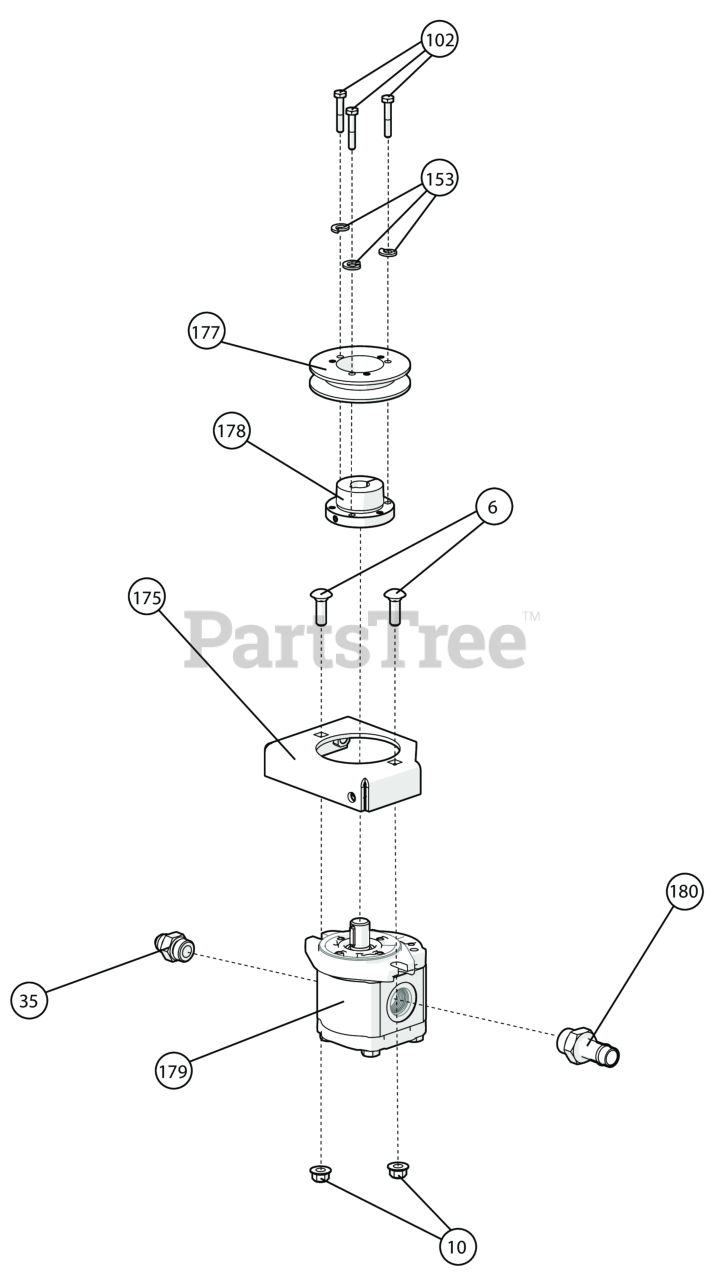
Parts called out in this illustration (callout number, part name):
6	BOLT CARRIAGE 3/8"-16 X 1 1/4" ZP
10	NUT-HEX-NYLK, FLG .375"-16 ZP
35	ADAPTER, HYDRAULIC, SAE-10 TO 1/2 JIC
102	SCREWCAP 1/4"-20X1 1/2" HCS ZP
153	WASHER LOCK 1/4" S/T MED
175	WA, HYDRAULIC PUMP MOUNT
177	PULLEY, QD, 4.00" OD
178	TUBE, PIVOT
179	PUMP, HYDRAULIC 10CC
180	ADAPTER, HYDRAULIC, SAE-12 TO 3/4 BEADED
